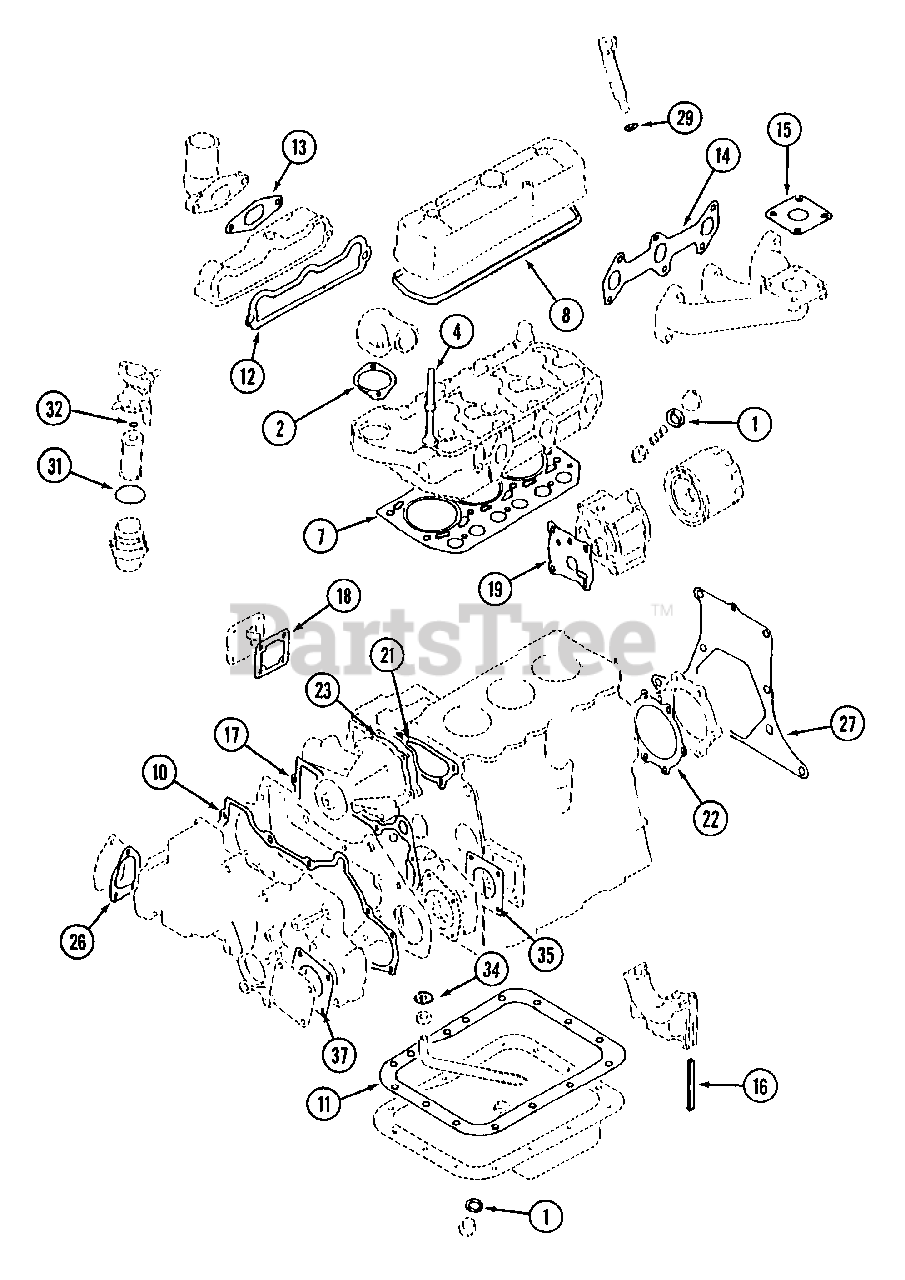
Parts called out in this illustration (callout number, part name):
1	Gasket, Drain-Plug
2	Gasket
4	Seal, Valve
7	Gasket, Cylinder
8	Gasket, Rocker Cover
10	Gasket, Gear Case
11	Gasket, Oil Pan
12	Gasket, Intake Manifold
13	Gasket, Inlet Pipe
14	Gasket, Exhaust Manifold
17	Gasket, Front Plate
18	Gasket, Cover
19	Gasket, Oil Pump
21	Gasket, Water
22	Gasket, Oil Seal
23	Gasket, Water Pump
26	Gasket Governor Cover
27	Gasket Rear Plate
29	Gasket, Nozzle Holder
31	O-Ring, Filter Cup
32	O-Ring, Element
34	Washer, Seal
35	Gasket, Oil Pump Cover
37	Gasket, Housing
